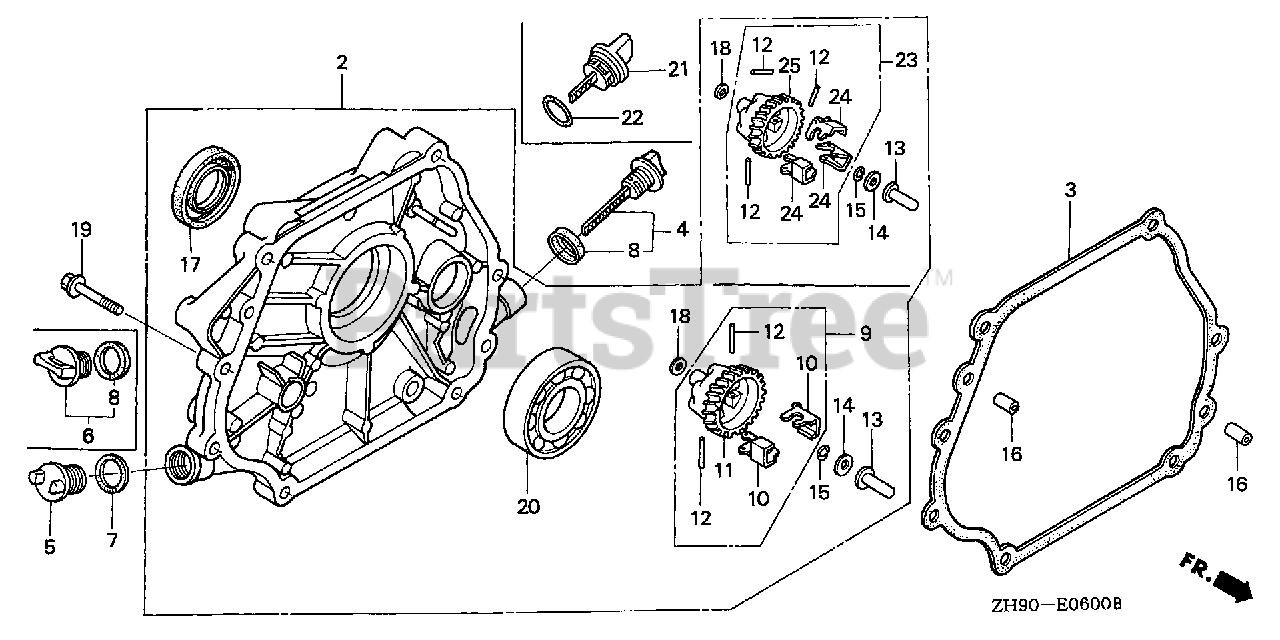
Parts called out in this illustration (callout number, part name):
2	COVER ASSY., CRANKCASE
3	GASKET, CASE COVER
4	CAP ASSY., OIL FILLER
6	CAP ASSY., OIL FILLER
8	GASKET, OIL FILLER CAP
9	GOVERNOR ASSY.
10	WEIGHT, GOVERNOR
11	HOLDER, GOVERNOR WEIGHT
12	PIN, GOVERNOR WEIGHT
13	SLIDER, GOVERNOR
14	WASHER (6X16)
15	CLIP, GOVERNOR HOLDER
16	PIN, DOWEL (8X12)
17	OIL SEAL (30X46X8)
18	WASHER, PLAIN (6MM)
20	BEARING, RADIAL BALL (6206)
